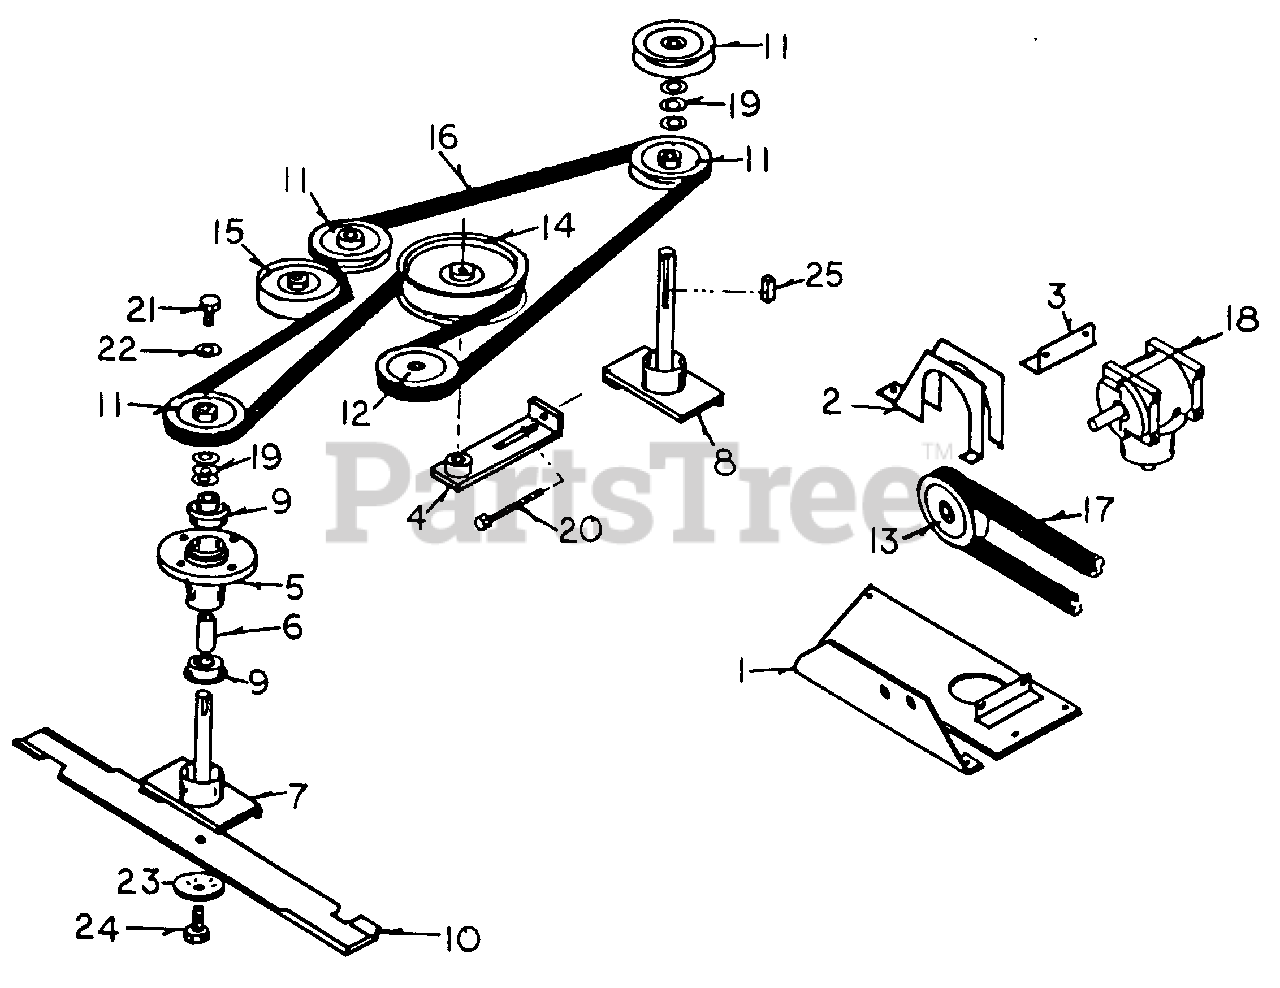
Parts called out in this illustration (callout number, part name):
1	Gearbox Mount
2	Belt Guard
3	Gearbox Mount Angle
4	Belt Tightener
5	Spindle Housing
6	Spindle Spacer
7	Spindle Shaft
8	Spindle Shaft, Long
9	Spindle Bearing
10	Blade
11	Spindle Pulley
12	Gearbox Pulley, Out Put
13	Gearbox Pulley, In Put
14	Idler Pulley, Large
15	Idler Pulley, Small
17	Deck Drive Belt
20	Adjustment Bolt
21	Hex Bolt, 5/16-24 x 8/4 0
22	Washer, 5/16, 10 0 Ga.
24	Hex Bolt, 3/8-24 x 1 1/4 0
25	Key Stock, 3/16"
